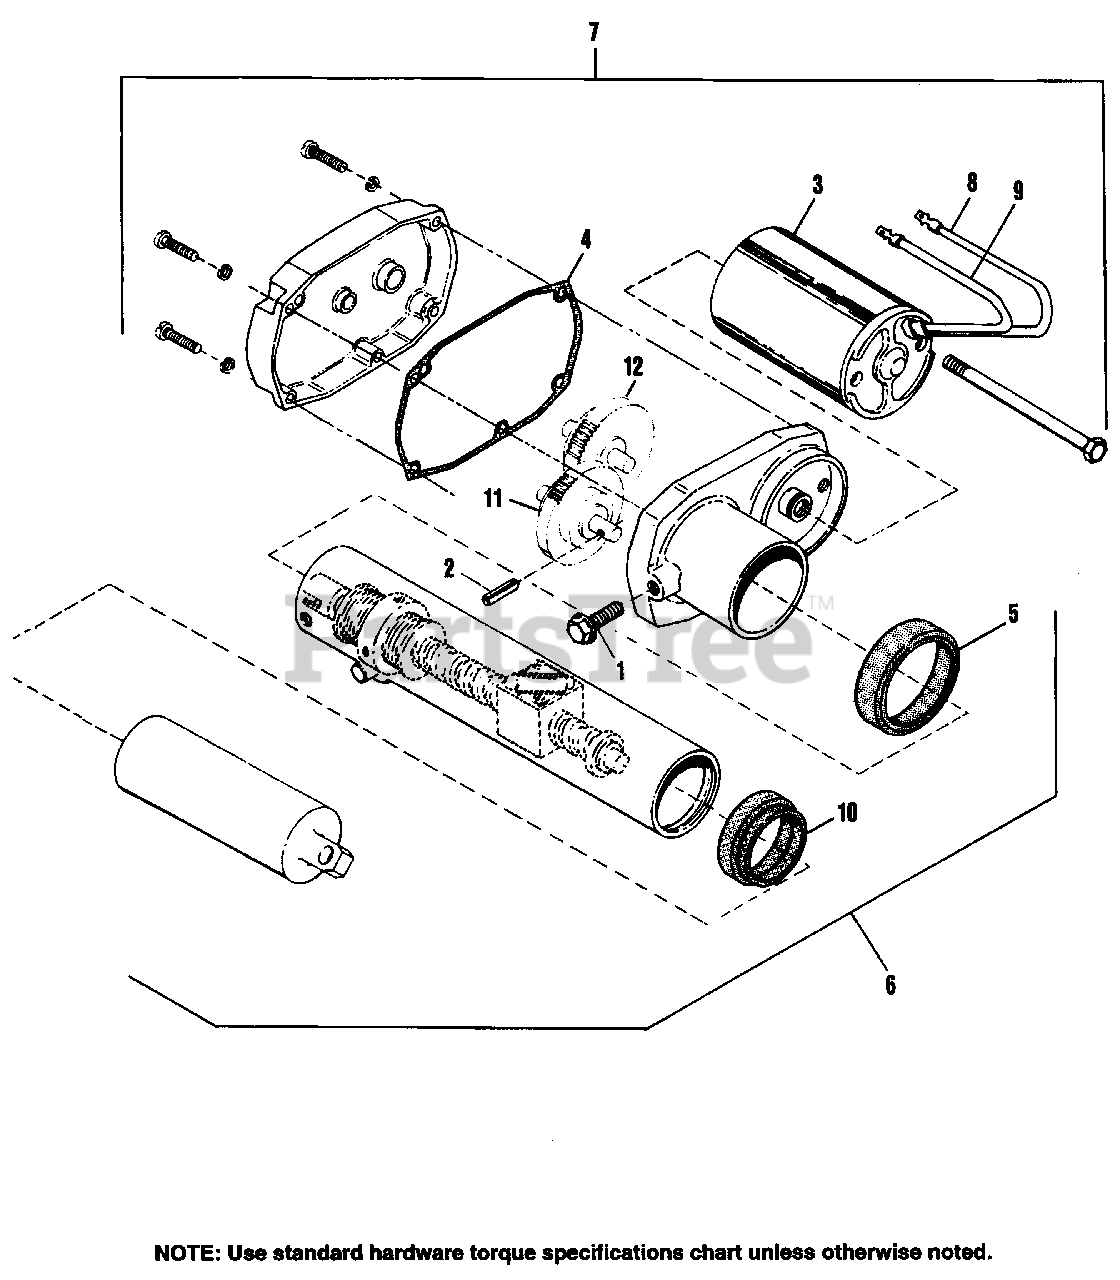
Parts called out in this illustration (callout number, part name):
1	CAPSCREW, Taptite
3	MOTOR KIT, 12 VDC
4	GASKET, Housing
5	SEAL, Outer Tube (Top)
6	BALL SCREW ASSY.
7	MOTOR & GEARBOX ASSY., 12 VDC, 17:1 Ratio
8	BRUSH & LEAD (Red)
9	BRUSH & LEAD (Black)
10	SEAL, Inner Tube (Top)
11	OUTPUT GEAR & SLIP CLUTCH ASSY.
12	GEAR ASSY., 2nd & 3rd
